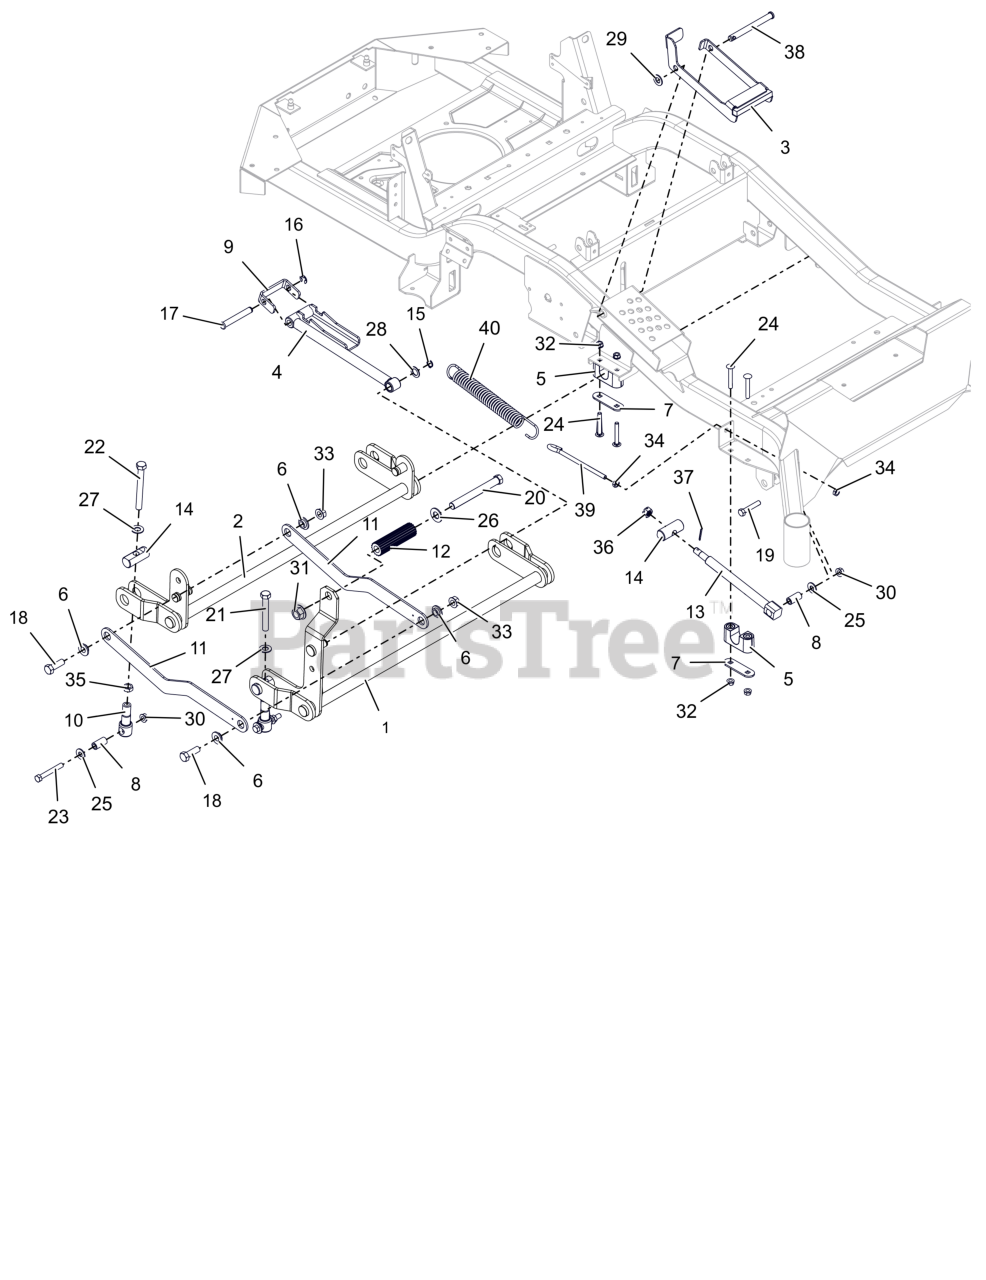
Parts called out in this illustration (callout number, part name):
1	WLDMT, FRONT DECK LIFT PIVOT
2	WLDMT, REAR DECK LIFT PIVOT
3	BRKT, HOC TRANSFER LOCK
4	WLDMT, HOC ARM
5	ASM-BUSHING, DECK LIFT
6	BSHG-FLG .515X.750X.395X1.120
7	PLATE, BEARING SUPPORT
8	SPACER, DECK LEVELING
9	BRKT, HOC LINE
10	LINK, DECK LIFT FORMED
11	LINK, DECK LIFT
12	ROD, FOOT PEDAL (BLACK)
13	DRAG,LINK-HD
14	PIN, DECK LIFT
15	RG-RTNG-EXT .625X.050
16	RG-RTNG-EXT .500X.042 (E)
17	PIN, .499/.494 x 3.385 CLEVIS
18	BLT,HEX .50-13X1.50 G5 ZCC
19	BLT,HEX .38-16X2.00 G5 ZCC
20	BLT, HEX .62-11X5.50 G5 FBP
21	BLT, HEX .50-13X3.50F G5 ZCC
22	BLT, HEX .50-13X4.50F G8 ZCC
23	BLT, HEX .38-16X2.75 G8 ZCC
24	BLT, RHSSN.31-18X2.25 G5 ZCC
25	WSHR,FLT .438X1.00X.083 ZCC
26	WSHRFLT 5/8SAE CARBHARD FBP
27	WSHR, FLT .557X1.040X.102 ZCC
28	WSHR, FLT .630X1.005X.062 ZCC
29	WSHR-FL-NYL .518X1.000X.080
30	NUT-LK-TOP-FLG .38-16 ZC120
31	NUT,FLG-TOP LK .625-11 FBP
32	NUT,LK-CTR-FLG .31-18 GF ZCC
33	NUT-LK-TOP-FLG .500-13 GF ZCC
34	NUT-JAM .375-16 G2 ZCC
35	NUT-JAM .500-13 G2 ZCC
36	NUT-SL .50-13
37	PIN,CTR.12X1.25EXTPRSQCT ZC120
38	PIN-SLIC .50X4.97X4.55 -ZCC
39	BOLT,.38-16 X 5.25-.62 DIA EYE
40	SG-TENS .162X1.25X8.25 WLD 25
